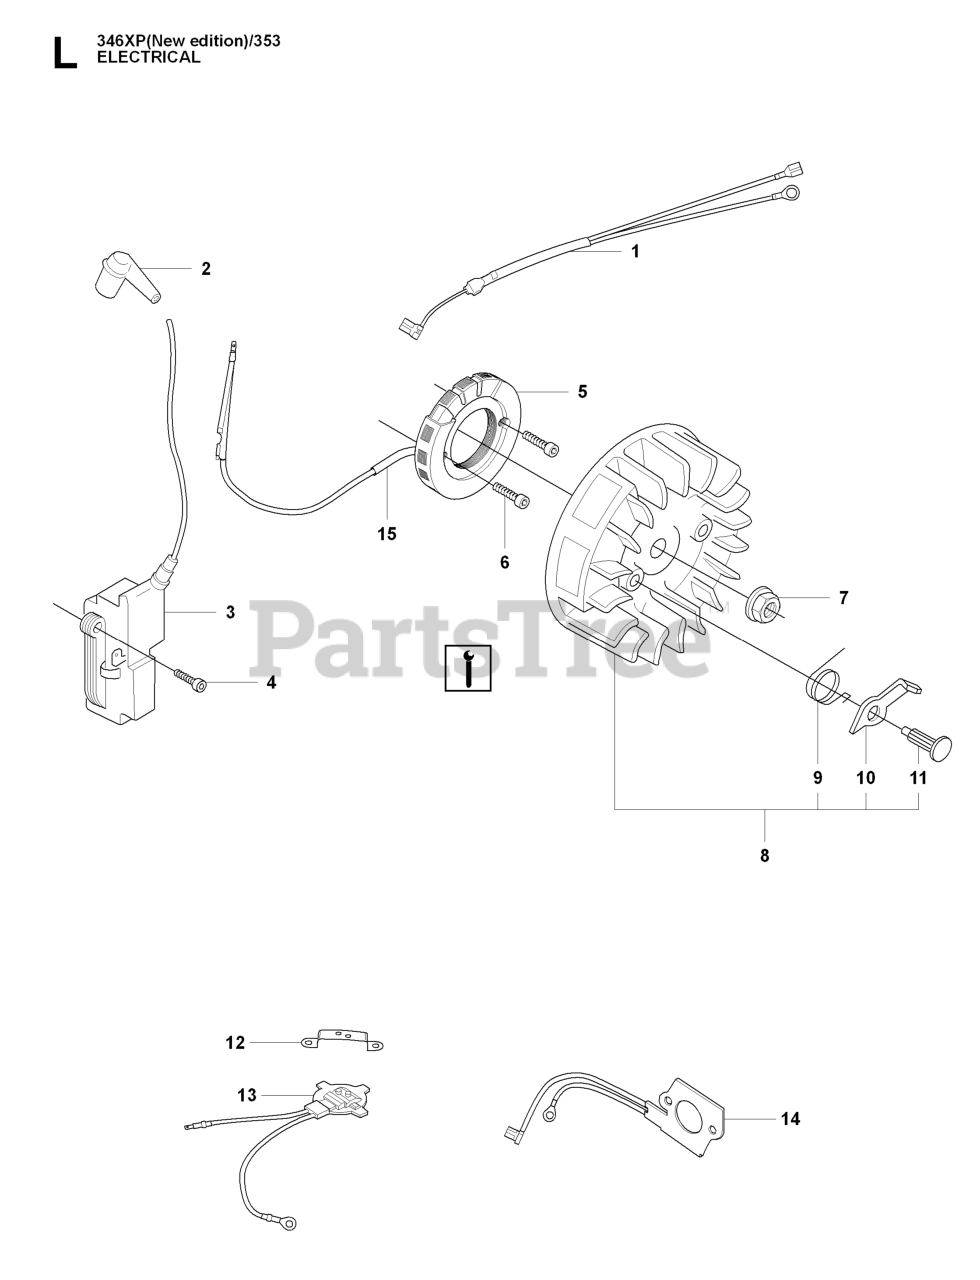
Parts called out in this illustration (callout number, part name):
1	WIRING ASSY
1	WIRING ASSEMBLY
2	SPARK PLUG CONN. KIT
3	IGNITION MODULE
3	%IGNITION MODULE
5	GENERATOR
5	GENERATOR STATOR
7	NUT W/ WASHER
8	RP FLYWHEEL
8	FLYWHEEL (G)
9	%SPRING, STARTER CATCH
10	PAWL
11	RIVET
12	RETAINER
13	THERMOSTAT ASSY
14	HEATING PLATE
15	CABLE COVER
